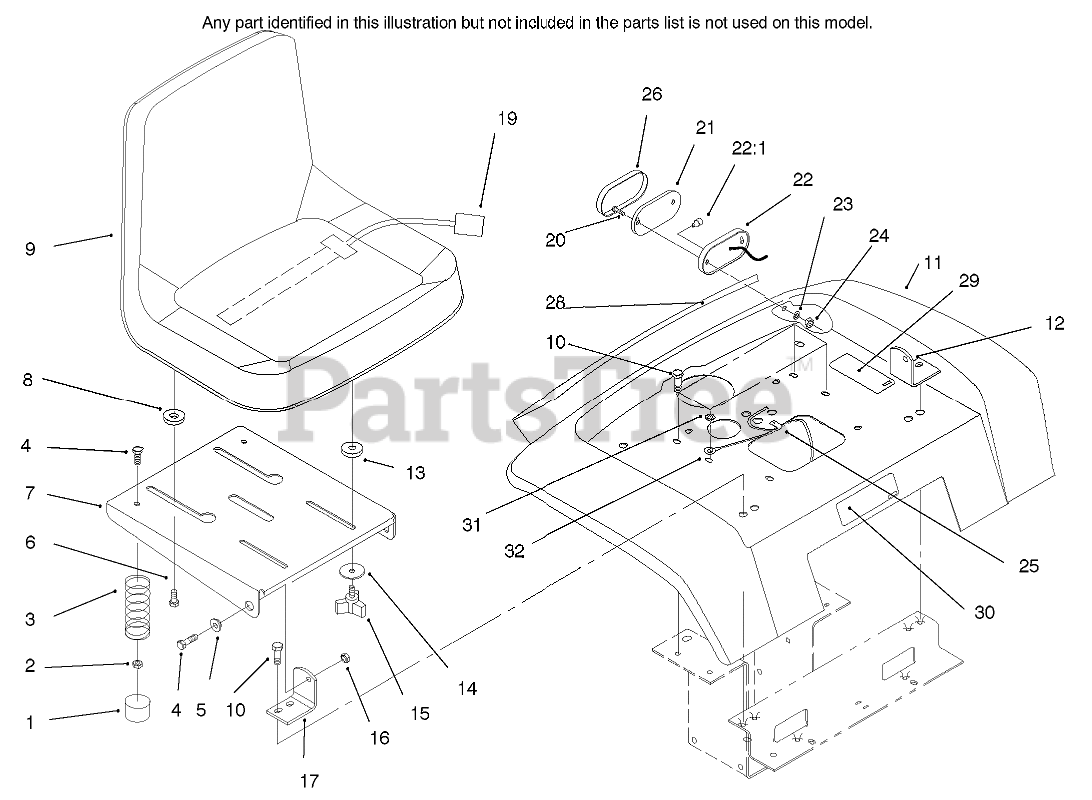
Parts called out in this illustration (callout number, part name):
1	CAP-PROTECTOR
2	NUT-LOCK, NI
3	SPRING-COMPRESSION
4	SCREW-HH
5	BUSHING
6	BOLT-SHOULDER
7	SUPPORT - SEAT (BLACK)
8	SPACER-NYLON
9	SEAT-V-511
10	Bolt
12	BRACKET-PIVOT, LH
13	SPACER-NYLON
14	WASHER
16	NUT-LOCK, NI
17	BRACKET-PIVOT, RH
19	SWITCH-SEAT
20	SCREW-PPH
22	BASE-TAIL LIGHT
23	WASHER-LOCK, INT
24	NUT-LOCK, NI
25	SPEED CLIP
26	LENS-TAIL LIGHT
28	DECAL - REAR FENDER
30	DECAL - USA
31	WASHER-LOCK
32	HARNESS - WIRE, MAIN
